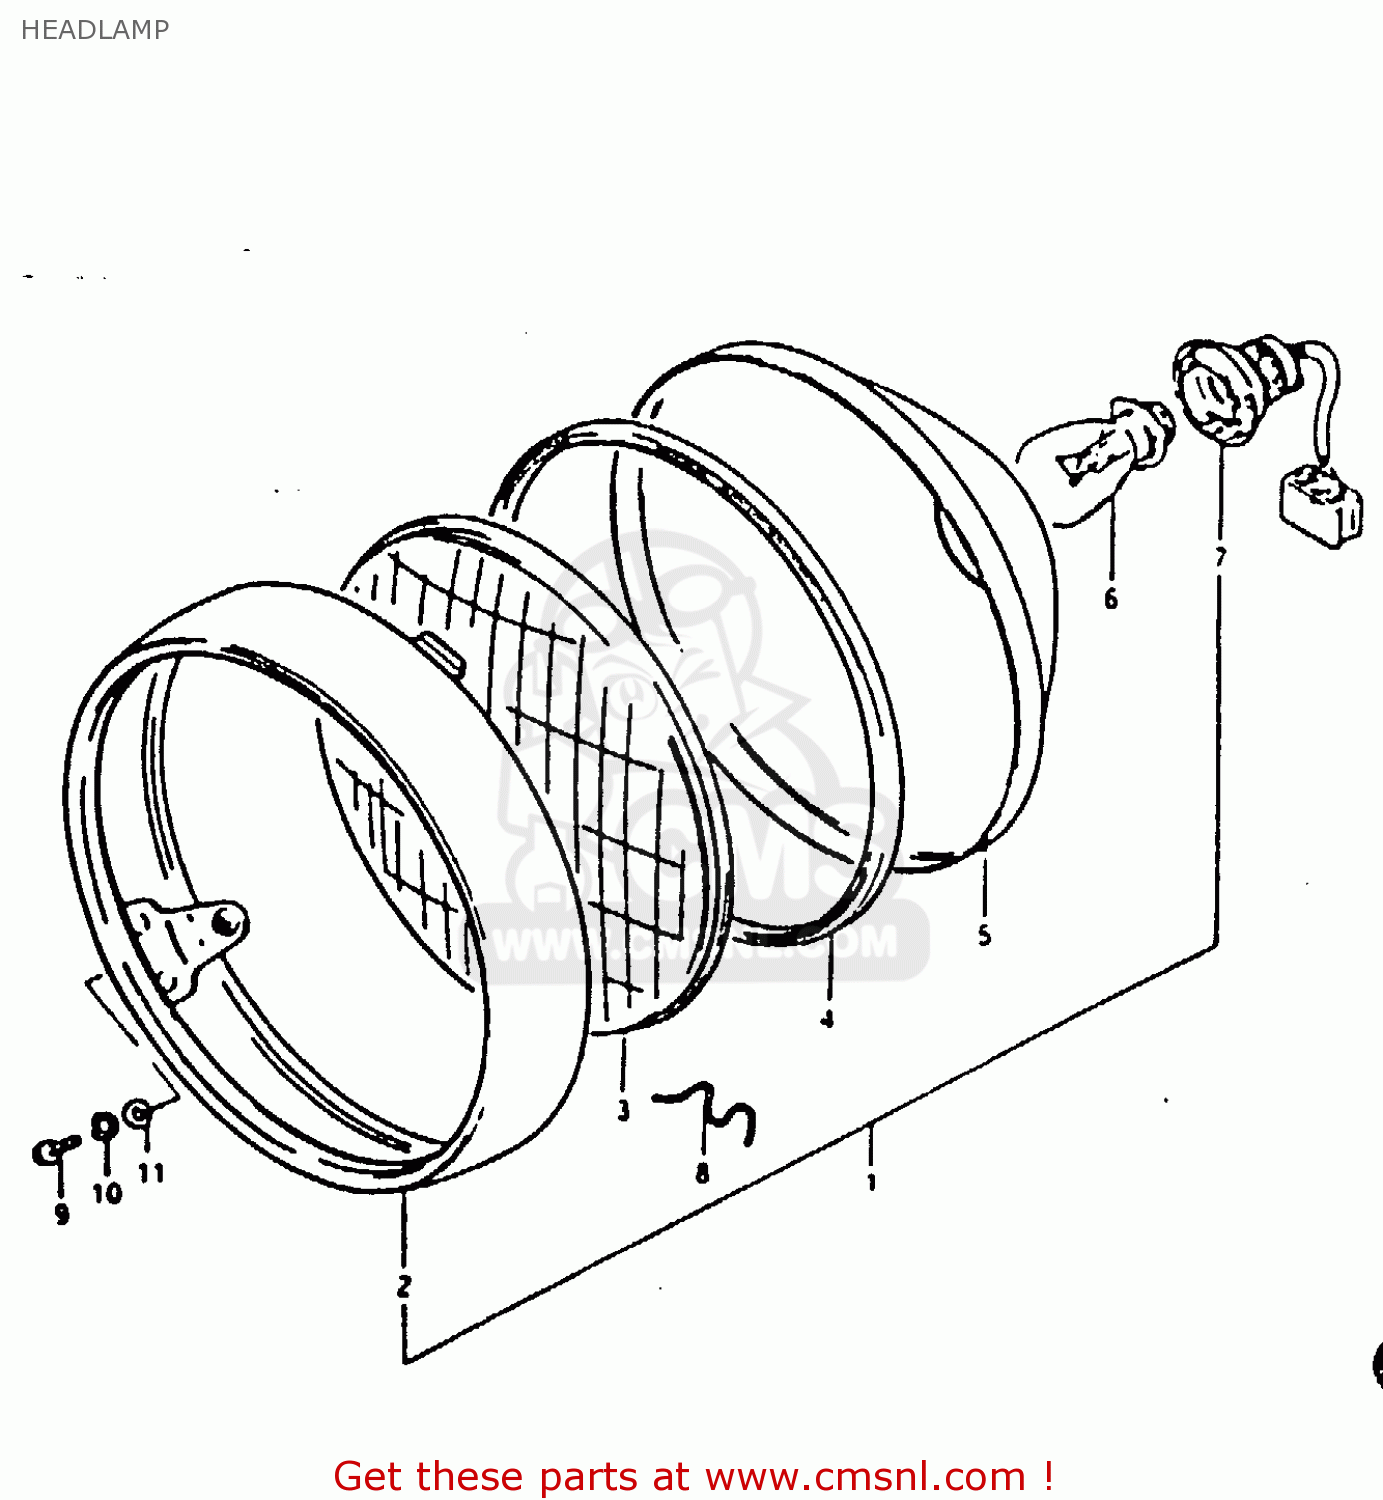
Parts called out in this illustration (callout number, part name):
1	HEADLAMP ASSY
2	RIM
3	LENS
4	GASKET (NAS)
5	REFLECTOR
6	BULB(6V25/25W,STANLEY,A7007)
7	SOCKET,HEADLAMP
8	SPRING
9	SCREW
10	LOCK WASHER
11	WASHER
